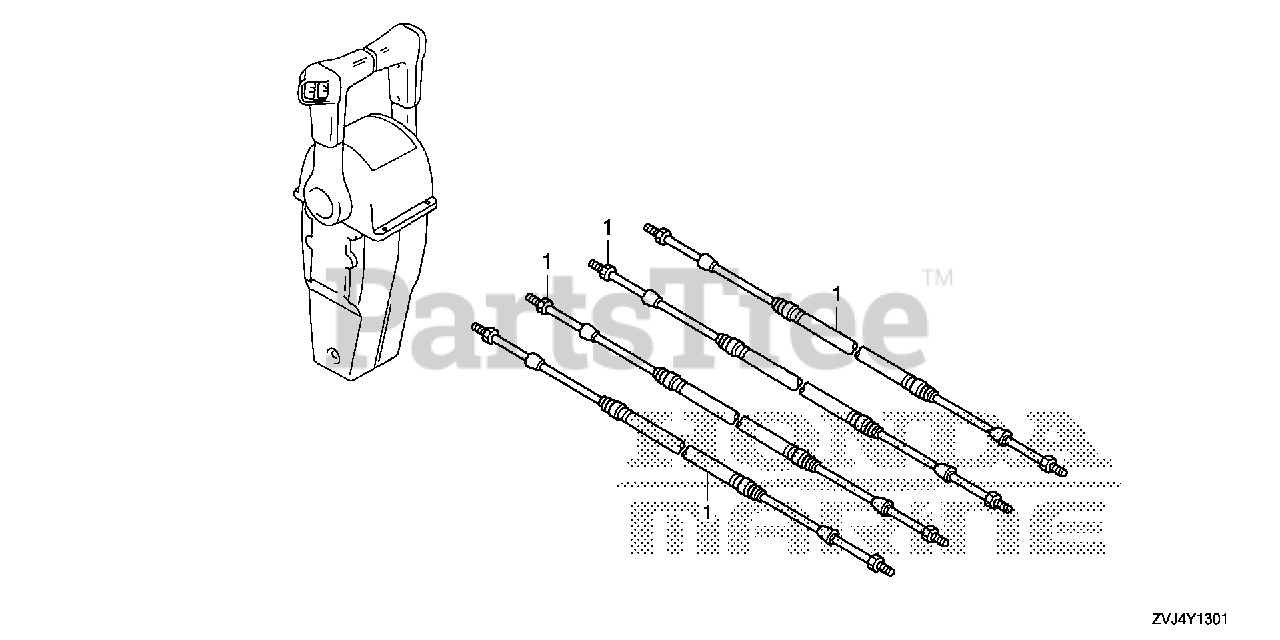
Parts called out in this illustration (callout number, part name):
1	CABLE, REMOTE CONTROL (10') (LOW FRICTION)
1	CABLE ASSY., PUSH-PULL (33C-5FT)
1	CABLE, REMOTE CONTROL (11') (LOW FRICTION)
1	CABLE ASSY., PUSH-PULL (33C-6FT)
1	CABLE, REMOTE CONTROL (12') (LOW FRICTION)
1	CABLE ASSY., PUSH-PULL (33C-7FT)
1	CABLE, REMOTE CONTROL (13') (LOW FRICTION)
1	CABLE ASSY., PUSH-PULL (33C-8FT)
1	CABLE, REMOTE CONTROL (14') (LOW FRICTION)
1	CABLE ASSY., PUSH-PULL (33C-9FT)
1	CABLE, REMOTE CONTROL (15') (LOW FRICTION)
1	CABLE ASSY., PUSH-PULL (33C-10FT)
1	CABLE, REMOTE CONTROL (16') (LOW FRICTION) (NOT AVAILABLE)
1	CABLE ASSY., PUSH-PULL (33C-11FT)
1	CABLE, REMOTE CONTROL (17') (LOW FRICTION)
1	CABLE ASSY., PUSH-PULL (33C-12FT)
1	CABLE, REMOTE CONTROL (18') (LOW FRICTION) (NOT AVAILABLE)
1	CABLE ASSY., PUSH-PULL (33C-13FT)
1	CABLE, REMOTE CONTROL (19') (LOW FRICTION)
1	CABLE ASSY., PUSH-PULL (33C-14FT)
1	CABLE, REMOTE CONTROL (20') (LOW FRICTION) (NOT AVAILABLE)
1	CABLE ASSY., PUSH-PULL (33C-15FT)
1	CABLE, REMOTE CONTROL (21') (LOW FRICTION)
1	CABLE ASSY., PUSH-PULL (33C-16FT)
1	CABLE, REMOTE CONTROL (22') (LOW FRICTION) (NOT AVAILABLE)
1	CABLE ASSY., PUSH-PULL (33C-17FT)
1	CABLE, REMOTE CONTROL (23') (LOW FRICTION)
1	CABLE ASSY., PUSH-PULL (33C-18FT)
1	CABLE, REMOTE CONTROL (24') (LOW FRICTION) (NOT AVAILABLE)
1	CABLE ASSY., PUSH-PULL (33C-19FT)
1	CABLE, REMOTE CONTROL (25') (LOW FRICTION)
1	CABLE ASSY., PUSH-PULL (33C-20FT)
1	CABLE, REMOTE CONTROL (26') (LOW FRICTION)
1	CABLE ASSY., PUSH-PULL (33C-21FT)
1	CABLE, REMOTE CONTROL (27') (LOW FRICTION)
1	CABLE ASSY., PUSH-PULL (33C-22FT)
1	CABLE, REMOTE CONTROL (28') (LOW FRICTION) (NOT AVAILABLE)
1	CABLE ASSY., PUSH-PULL (33C-23FT)
1	CABLE, REMOTE CONTROL (29') (LOW FRICTION)
1	CABLE ASSY., PUSH-PULL (33C-24FT)
1	CABLE, REMOTE CONTROL (30') (LOW FRICTION) (NOT AVAILABLE)
1	CABLE ASSY., PUSH-PULL (33C-25FT)
1	CABLE, REMOTE CONTROL (31') (LOW FRICTION)
1	CABLE ASSY., PUSH-PULL (33C-26FT)
1	CABLE, REMOTE CONTROL (32') (LOW FRICTION) (NOT AVAILABLE)
1	CABLE ASSY., PUSH-PULL (33C-27FT)
1	CABLE, REMOTE CONTROL (33') (LOW FRICTION)
1	CABLE ASSY., PUSH-PULL (33C-28FT)
1	CABLE, REMOTE CONTROL (34') (LOW FRICTION) (NOT AVAILABLE)
1	CABLE ASSY., PUSH-PULL (33C-29FT)
1	CABLE, REMOTE CONTROL (35') (LOW FRICTION)
1	CABLE ASSY., PUSH-PULL (33C-30FT)
1	CABLE ASSY., PUSH-PULL (33C-31FT)
1	CABLE ASSY., PUSH-PULL (33C-32FT)
